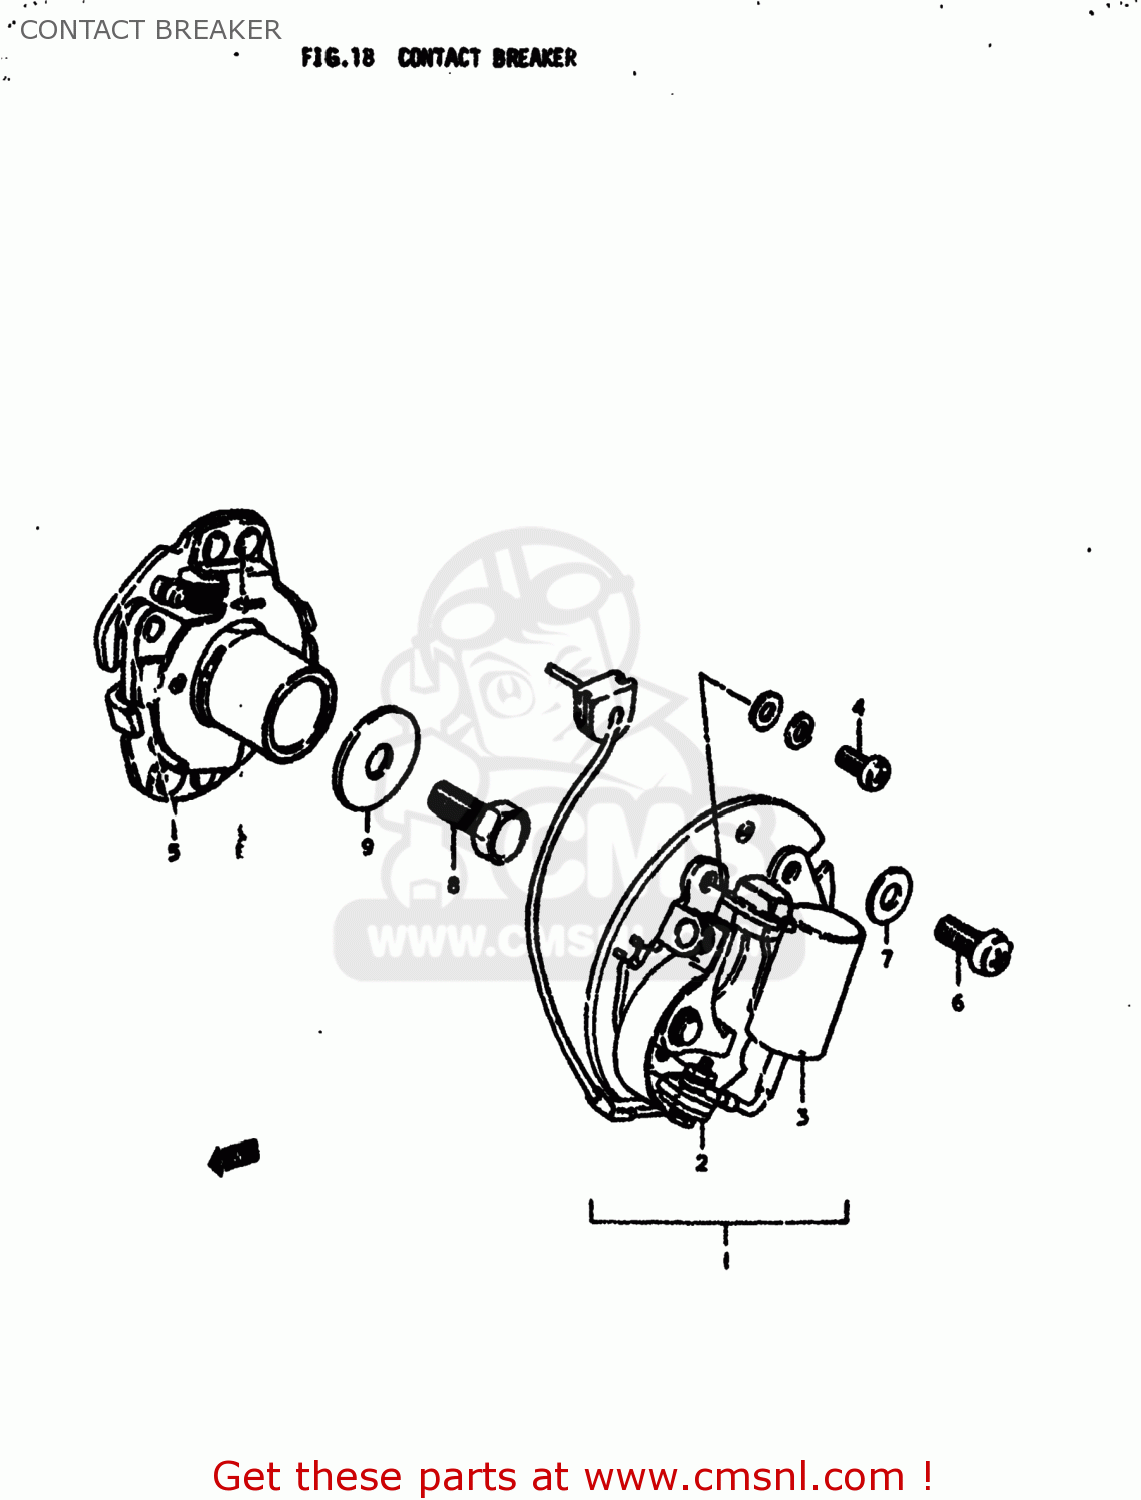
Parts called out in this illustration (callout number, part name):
1	STATOR,SIGNAL GENERATOR
2	POINT ASSY,CONTACT
3	CONDENSER
4	SCREW
5	GOVERNOR ASSEMBLY
6	SCREW(5X12)
7	WASHER
8	BOLT, UPPER
9	WASHER (6X20X1.5)
